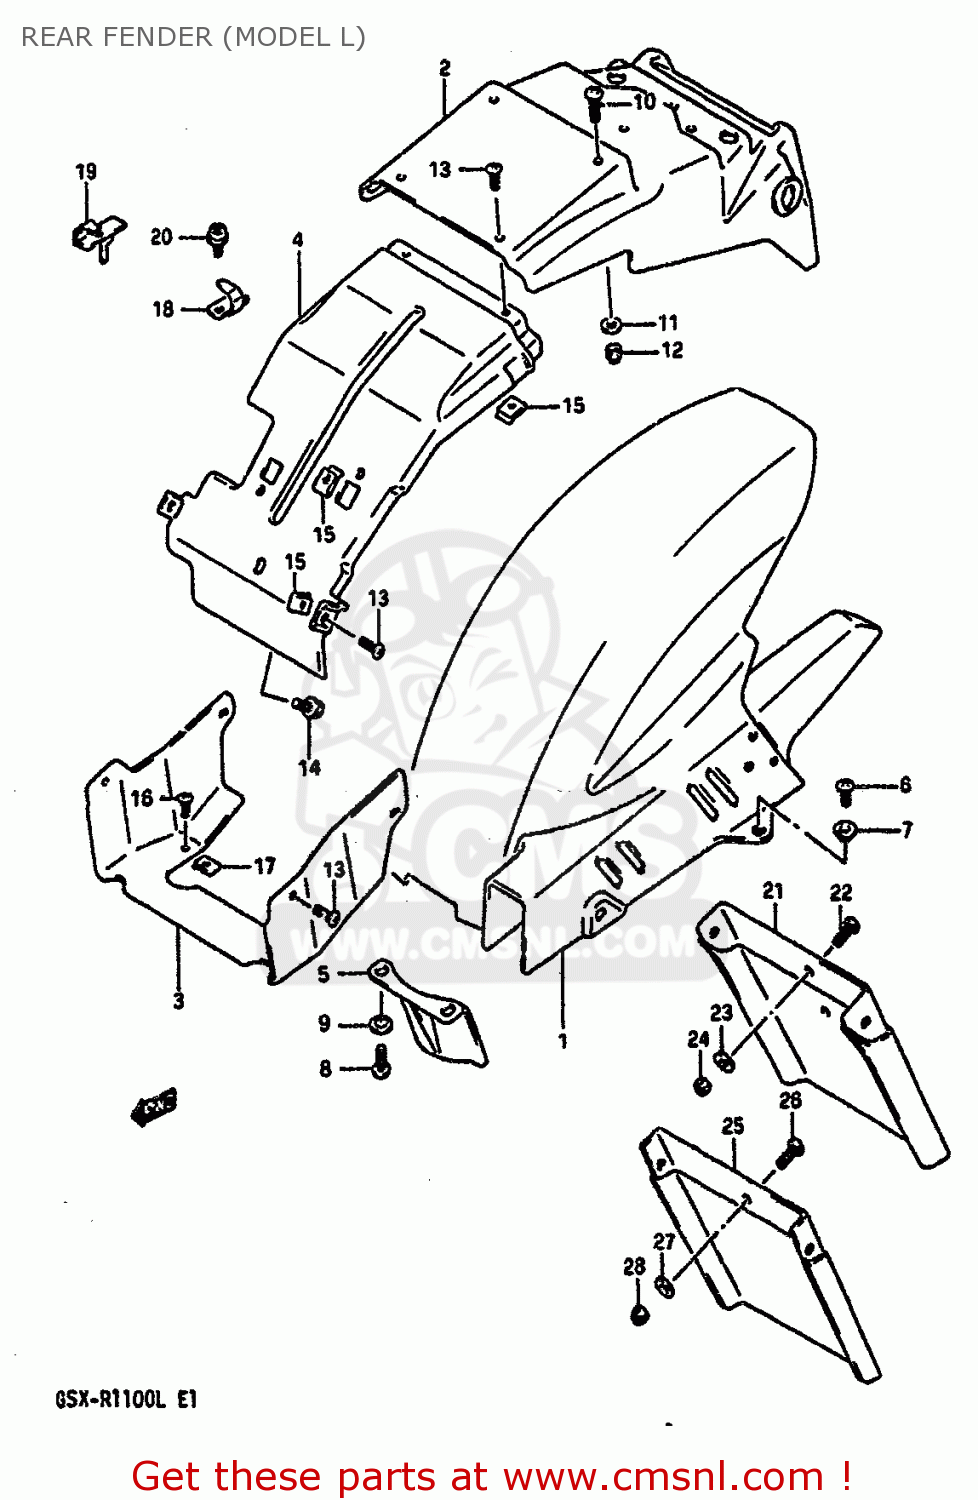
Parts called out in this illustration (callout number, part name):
1	FENDER,RR LWR
2	FENDER,RR UPR
3	FENDER,REAR
4	FENDER,RR UPR FR NO.2
5	GUARD,RR UNIT MUD
6	SCREW
7	WASHER
8	SCREW
9	WASHER,LOCK
10	SCREW
11	WASHER
12	NUT 6MM
13	SCREW, FRONT & REAR
14	BOLT
15	NUT,HEADLAMP HOUSING,UPPER
16	SCREW, FRONT & REAR
17	NUT,HEADLAMP HOUSING,UPPER
18	HOLDER,HELMET
19	HOLDER,HELMET,RIGHT
20	BOLT
21	EXTENSION, REAR FENDER
22	SCREW
23	WASHER
24	NUT 6MM
25	MUD GUARD,REAR FENDER
26	SCREW
27	WASHER
28	NUT 6MM
